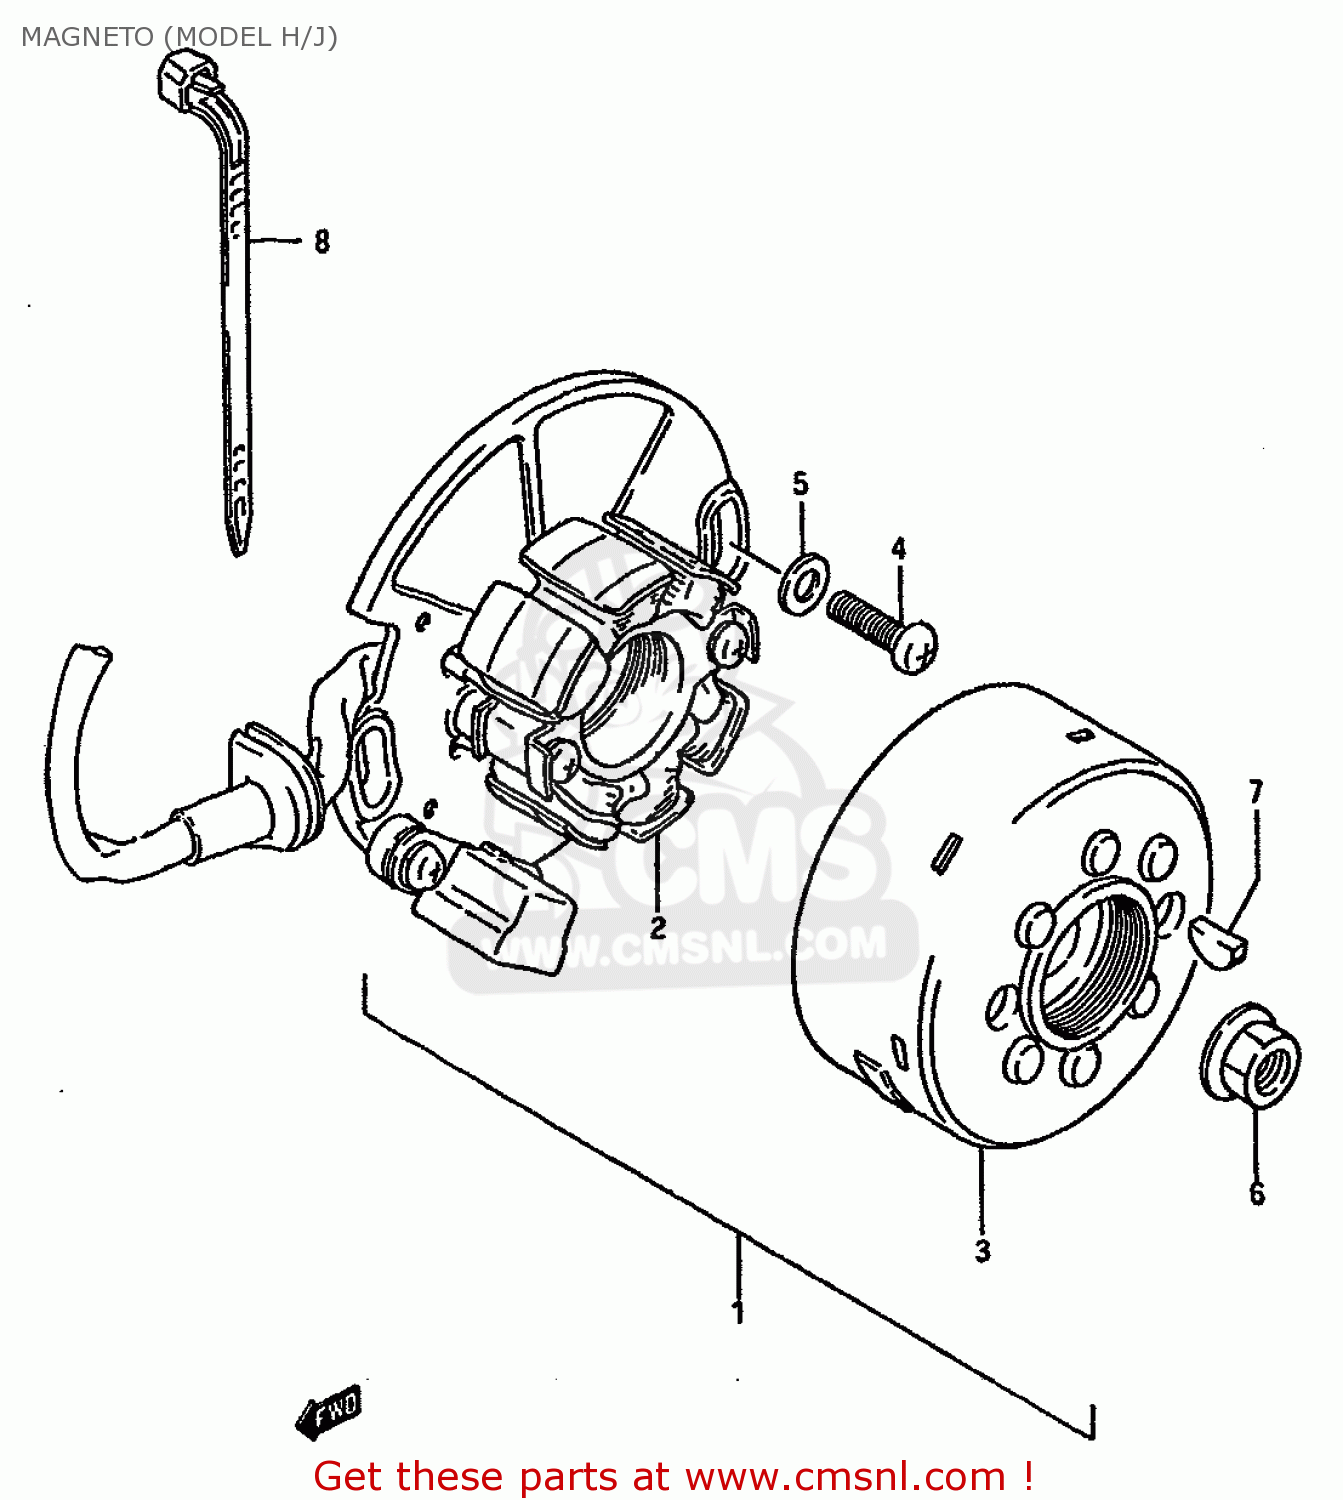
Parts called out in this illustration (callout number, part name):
1	MAGNETO ASSEMBLY
2	STATOR ASSEMBLY
3	ROTOR
4	SCREW
5	WASHER
6	NUT
7	KEY 4MM
8	CLAMP(L:125)
